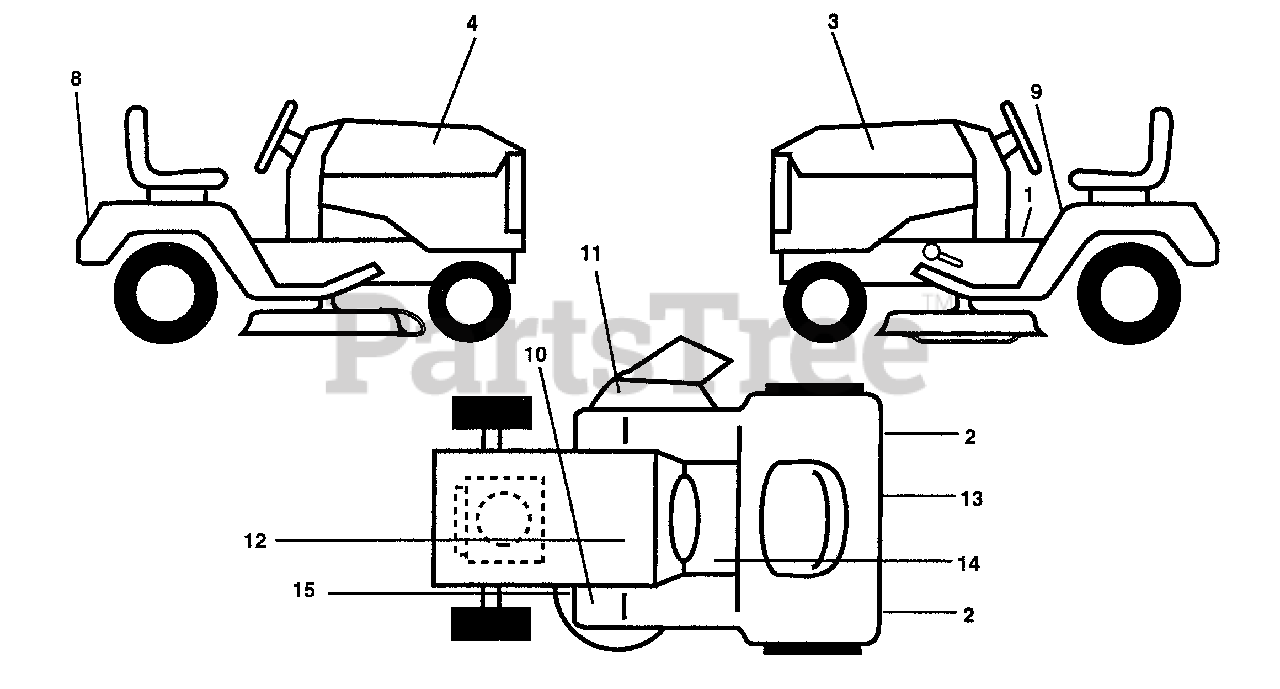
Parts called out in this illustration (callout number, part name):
1	Decal Instruction Dash Eng/fr
2	Reflector Tail Light Red/amber
3	Decal Hood LH Husq P/L YTH180
4	Decal Hood RH Husq P/L YTH180
8	Decal Fender Logo Husq
9	Decal Caution Fender Eng/fr
10	Decal Clutch/brake Eng/fr
11	Decal Warning Multi-Language
12	Decal Bat Dan/Poi P/L Sym
13	Decal Drawbar CNTRL MVT HYD LT
14	Decal SDL COLD START HYD E/F
15	Decal V-Belt Schematic44" 46" 50"Vented
